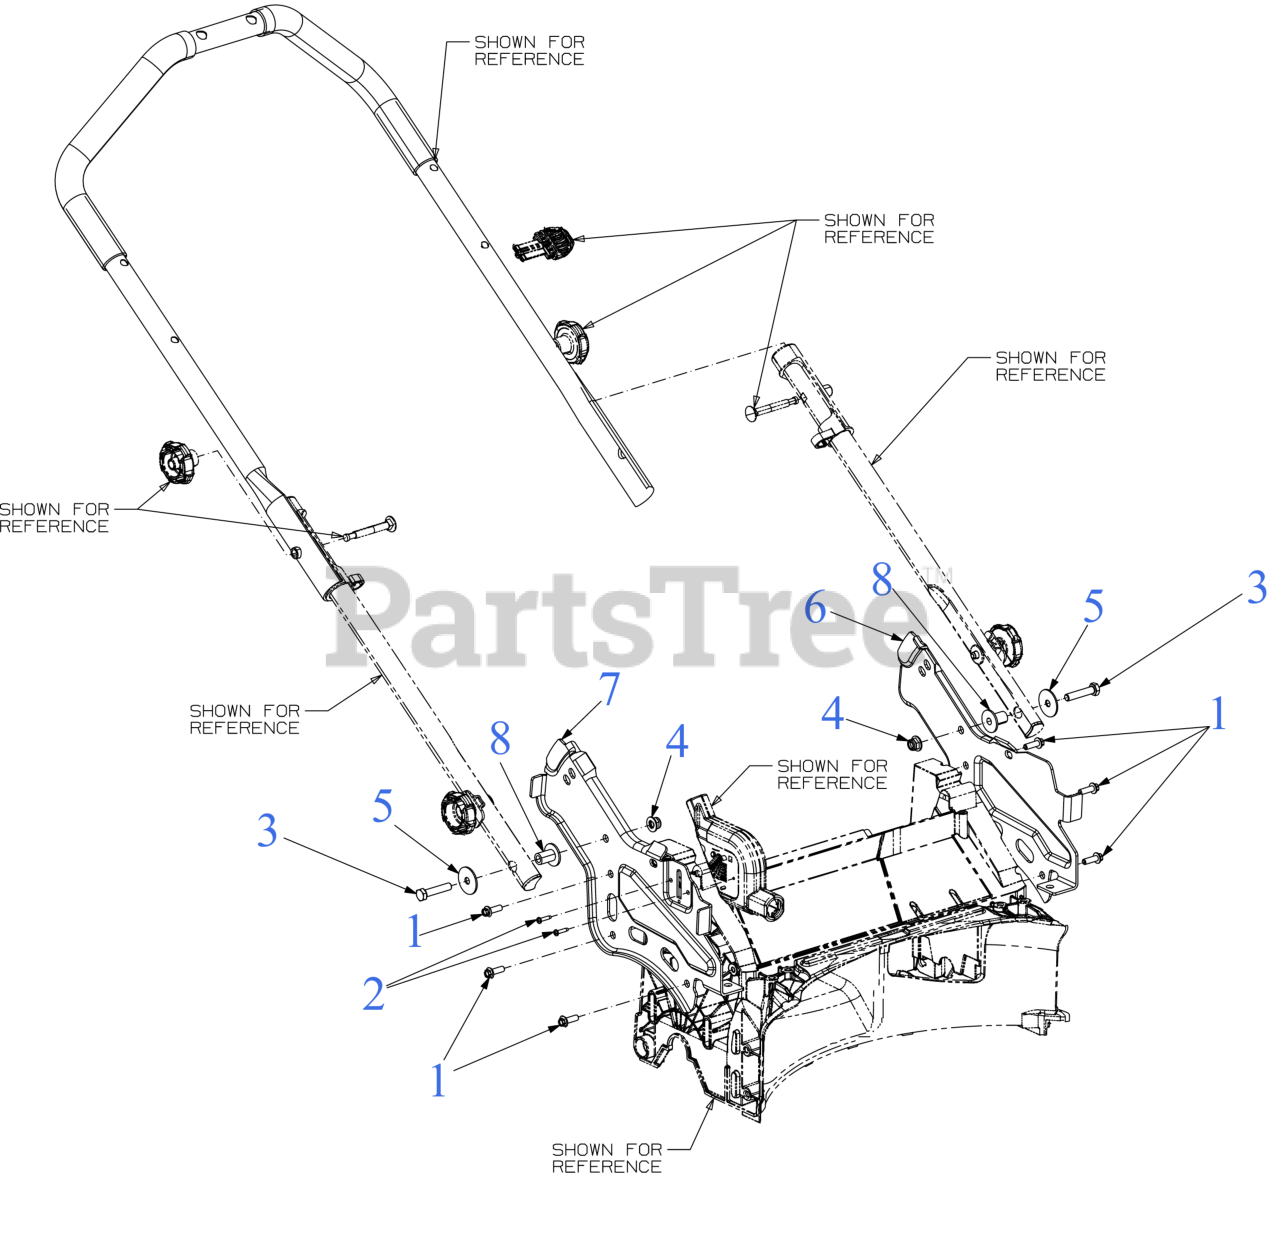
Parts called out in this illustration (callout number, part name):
1	SCREW 1/4 x .750
2	SCREW-TAP PLASTIC #6-19 X 0.62
3	SCREW 5/16-18 x 1.5 LG
4	FLANGE LOCK NUT 5/16-18
5	FLAT WASHER 0.315x1.255x0.060 HD
6	HANDLE BRACKET (LH)
7	HANDLE BRACKET (RH)
8	SHOULDER SPACER 0.3146x1.0236x0.0708
